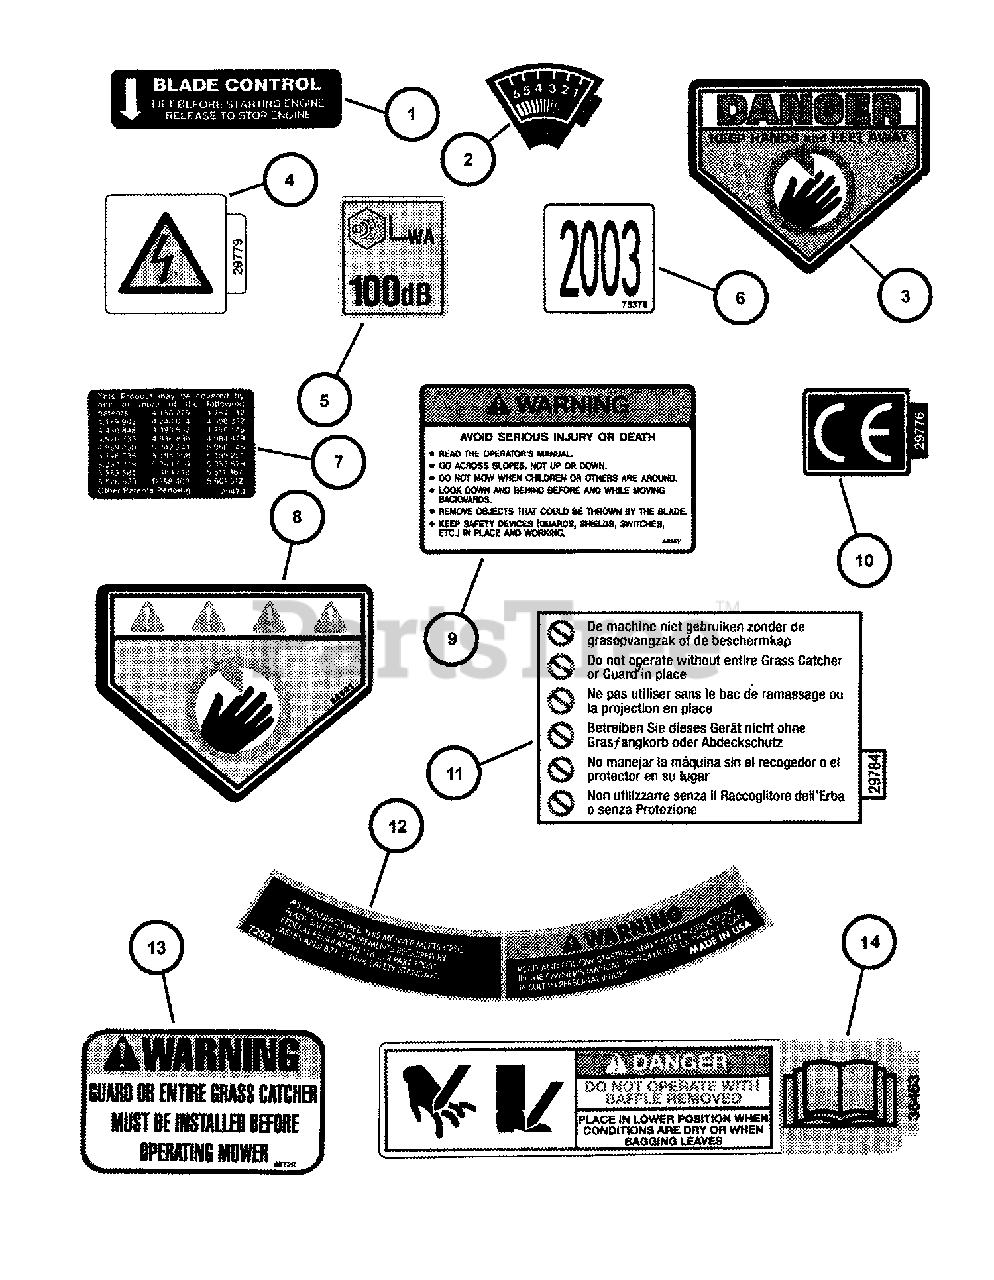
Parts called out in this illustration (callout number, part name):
1	DECAL, Blade Control
2	DECAL, Speed Select
3	DECAL, Danger, Cut Finger
4	DECAL, Spark Plug International Symbol
5	DECAL, Noise (European)
7	DECAL, Patent Numbers
8	DECAL, Warning (Euro)
9	DECAL, Warning
10	DECAL, Euro Community (CE)
11	DECAL, Deck/Chute (European)
12	DECAL, Deck Warning
13	DECAL, Warning Chute/Deflector
14	DECAL, Front Baffle
